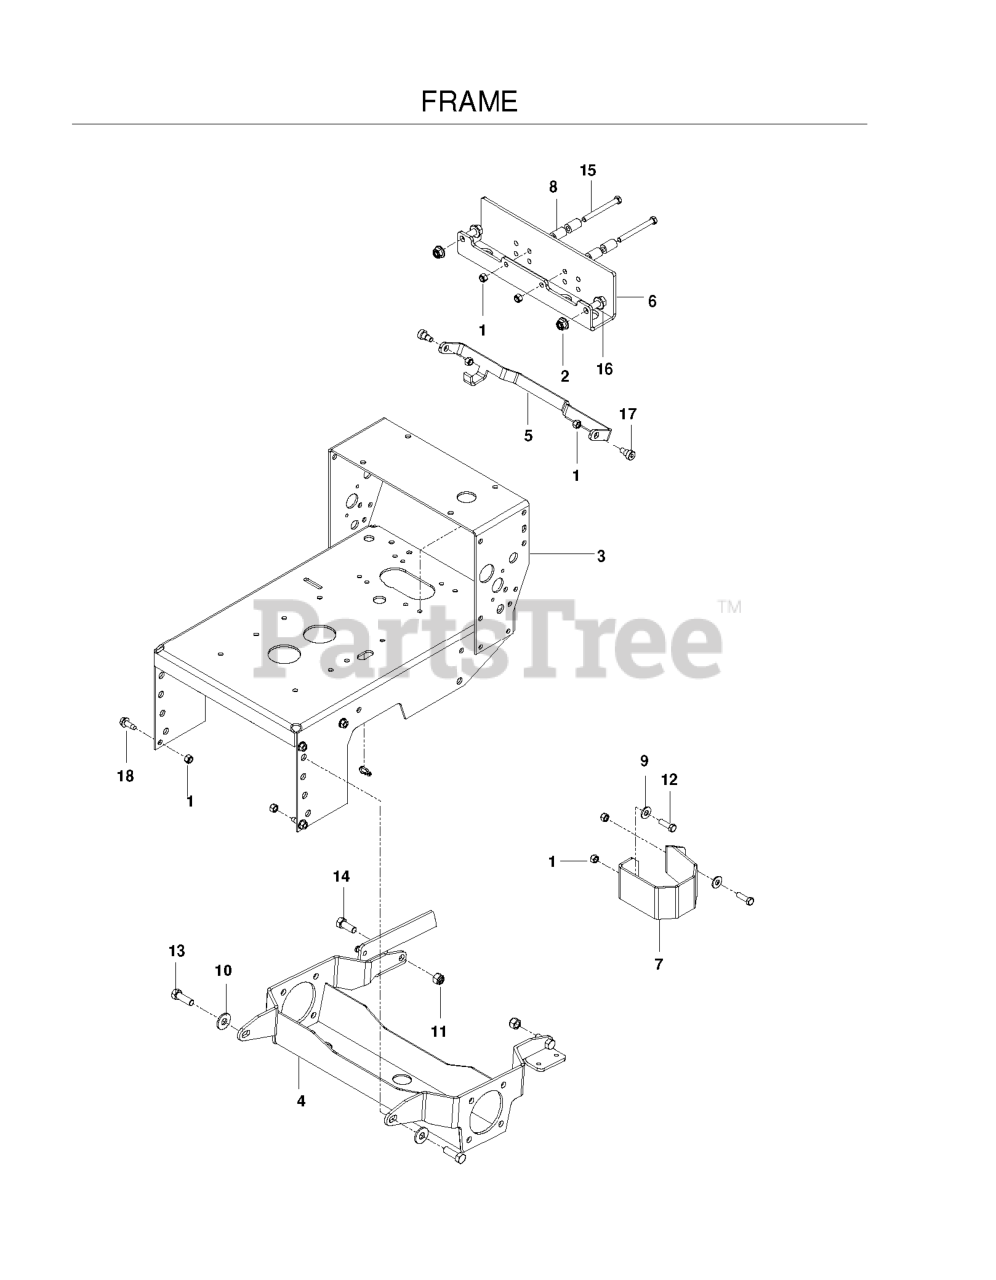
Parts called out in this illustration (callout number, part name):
1	NUT 3/8-16 NYLOC
2	NUT, 1/2-13 HEX FLG NYLOC ZD
3	ENGINE CHASSIS W/DECAL
4	AXLE HYDRO
5	BAR, THROWOUT OR
6	BUMPER, OR
7	GUARD FILTER PAINTED
9	WASHER 3/8 FLAT
10	WASH USS FLAT 1/2
11	NUT 1/2-13 HEX NYLOC ZD
12	HCS 3/8C X 1 1/4 GR5
13	HCS 1/2-13 X 1-1/2 GR 5 ZD
14	HCS 1/2-13 X 1-1/4
15	HCS3/8-16.X
16	HHFS 1/2-13 X 1 GR5 ZD
17	SB 3/8-16 X 3/8 SKT HD ZD
18	BOLT 3/8-16 X 1.0
